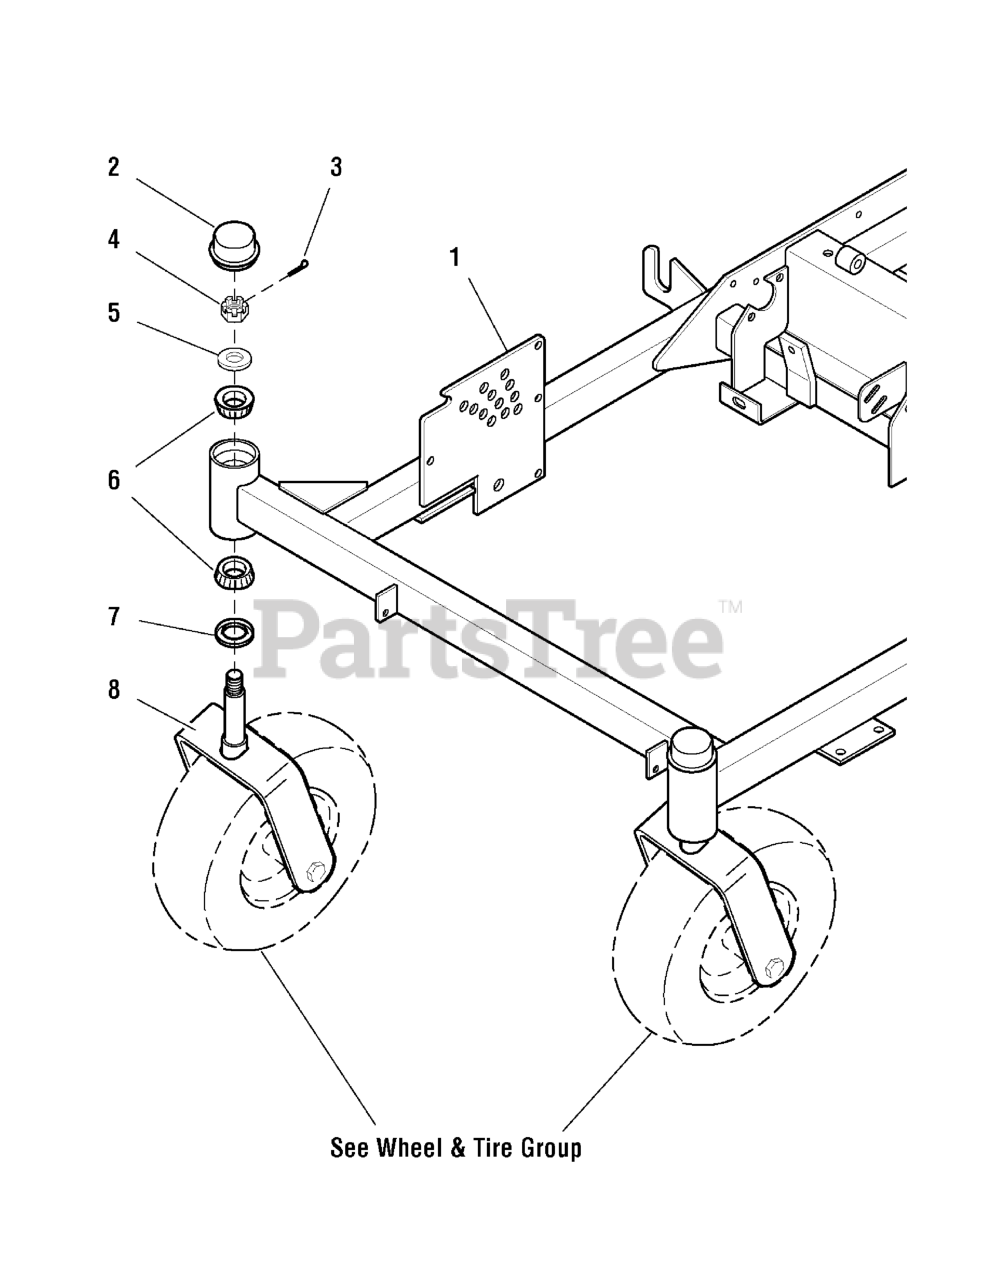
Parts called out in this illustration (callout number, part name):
1	MAIN FRAME
2	CAP
3	PIN, COTTER, 1/8 X 1-1/4
4	NUT, Hex, Slotted, 3/4-16
5	WASHER, 3/4 SAE
6	BEARING, Tapered Roller
7	SEAL, GREASE
8	CASTER YOKE
